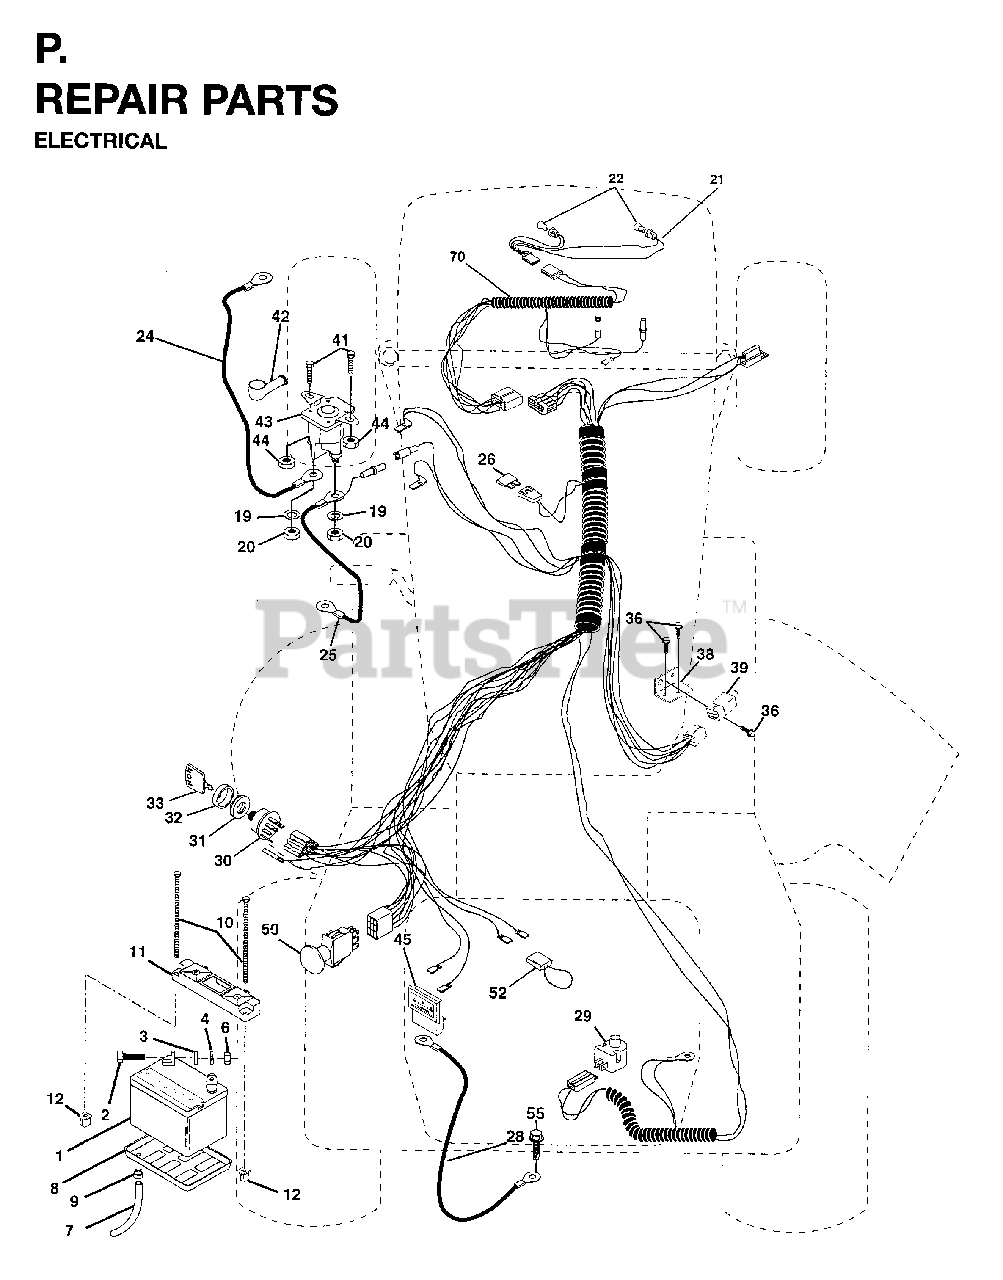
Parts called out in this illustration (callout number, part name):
1	BATTERY 12 VOLT 30 AMP WET
4	LOCKWASHER
6	NUT
7	PLASTIC TUBE
8	TRAY.BATTERY
9	HOSE CLAMP T
10	BOLT 1/4-20 X 7.5
11	HOLDDOWN, BATTERY, DASH MOUNT
12	NUT, PUSH NYLON 1/4" BATTERY
19	LOCKWASHER
20	NUT
21	HARNESS ASM HDLIG
22	LIGHTBULB
24	BATTERY CABLE
25	CABLE BATTERY 6 GA 22" W/16W
28	CABLE GROUND 6 GA 21" 90T BLK
29	SWITCH SEAT
30	SWITCH.IGNITION.4.POSITION
31	NUT IGNITION
32	COVER SWITCH KEY
33	KEY SET
38	SWITCH BRACKET
39	SWITCH INTERLOCKT
41	BOLT
42	TERMINAL COVER
43	KIT SOLENOID .95
44	NUT.CROWNLOCK.1/4
50	SWITCH-PTO
52	WIRE PROTECTION LOOP
70	HARNESS, ENGINE
